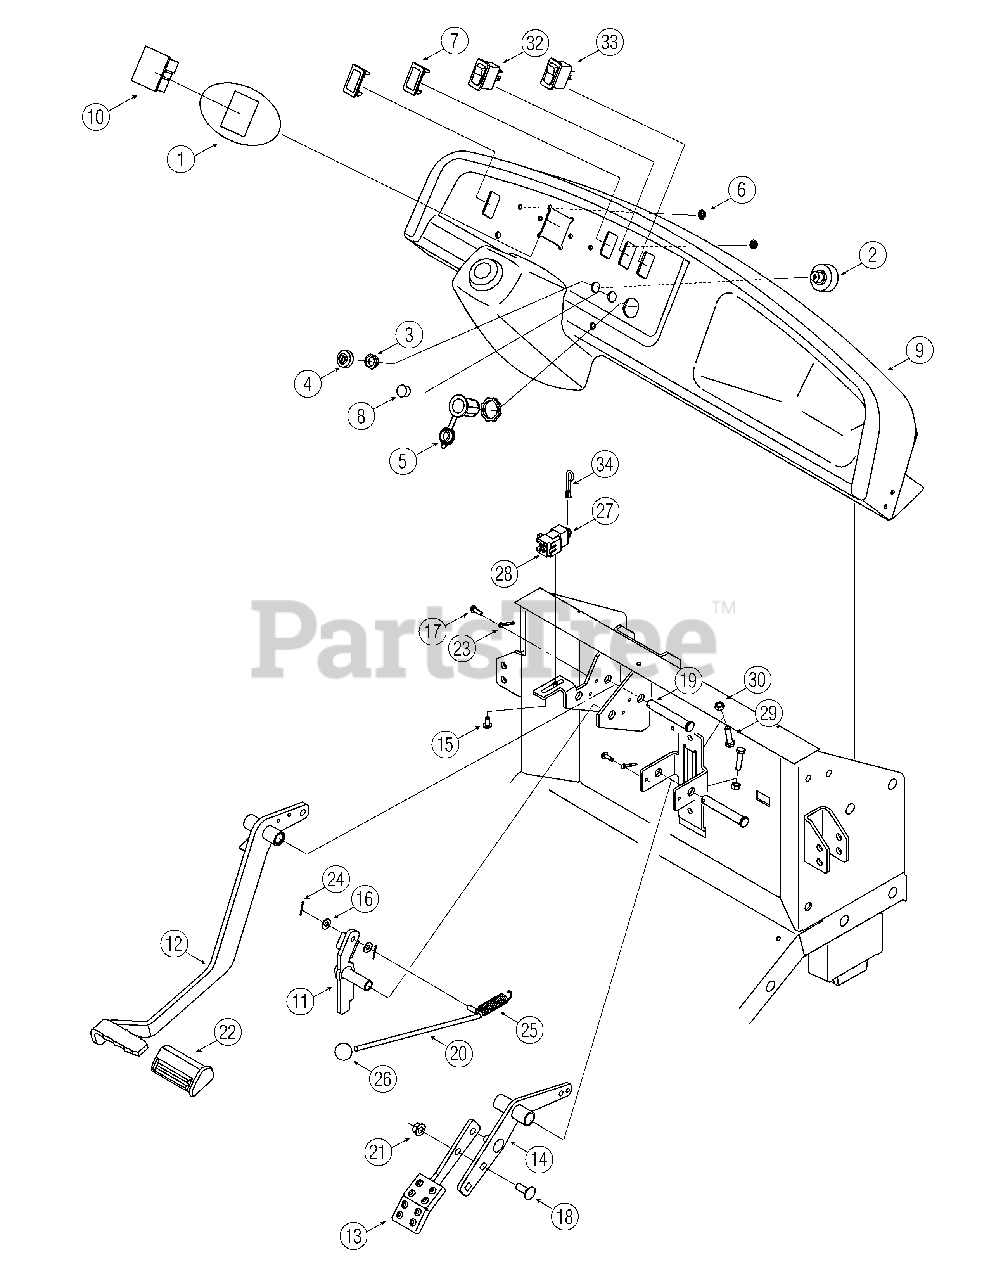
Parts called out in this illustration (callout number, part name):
1	Instrument Dash Cover
2	Key Switch
3	Nut, Ignition Switch, 5/8-32
4	Cap, Ignition Switch
5	Power Receptacle, 12V
6	Nut, Retainer, 1/8
7	Switch Plug Panel
8	Plug, Horn Switch
9	Dash Panel
10	Hour Indicator Meter
11	Lever, Parking Brake
14	Pedal Arm Assembly, Throttle
15	Screw, Hi-Lo, 1/4-20 x .5
16	Washer, Flat .25 x .630 x .0515
17	Screw, Self-tapping, #10-32 x.625
18	Bolt, Carriage, 3/8-16 x 1.0
19	Pin, Clevis.50 x 3.25
20	Rod, Brake Lock
21	Nut, Flange Lock, 3/8-16
22	Pad, Brake Pedal
23	Pin, Cotter, 5/32 x 1.00
24	Pin, Cotter, 1/16
25	Spring, Extension, .637 x 2.972
26	Knob, Ball
27	Cover, Protective
28	Snap Mount Switch, Interlock
29	Hex Screw, 5/16-18 x 1.25
30	Hex Nut, 5/16-18
32	Bed Lift Switch
33	Power Receptacle Switch
34	Cotter Pin
